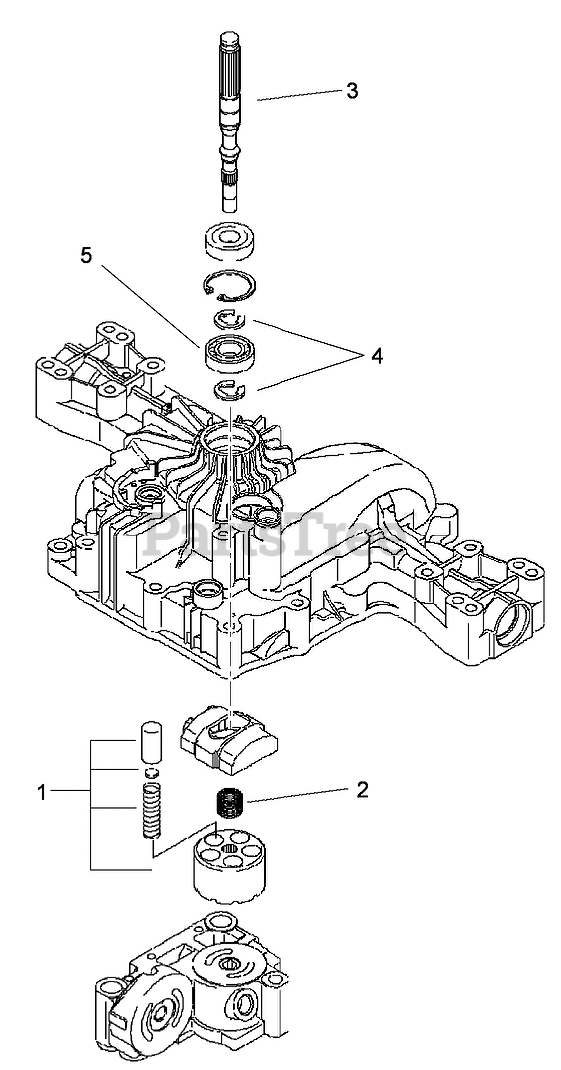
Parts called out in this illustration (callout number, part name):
1	Block-Cylinder
2	Spring-Pump
3	Shaft-Pump
4	E-RING
5	BEARING-BALL
